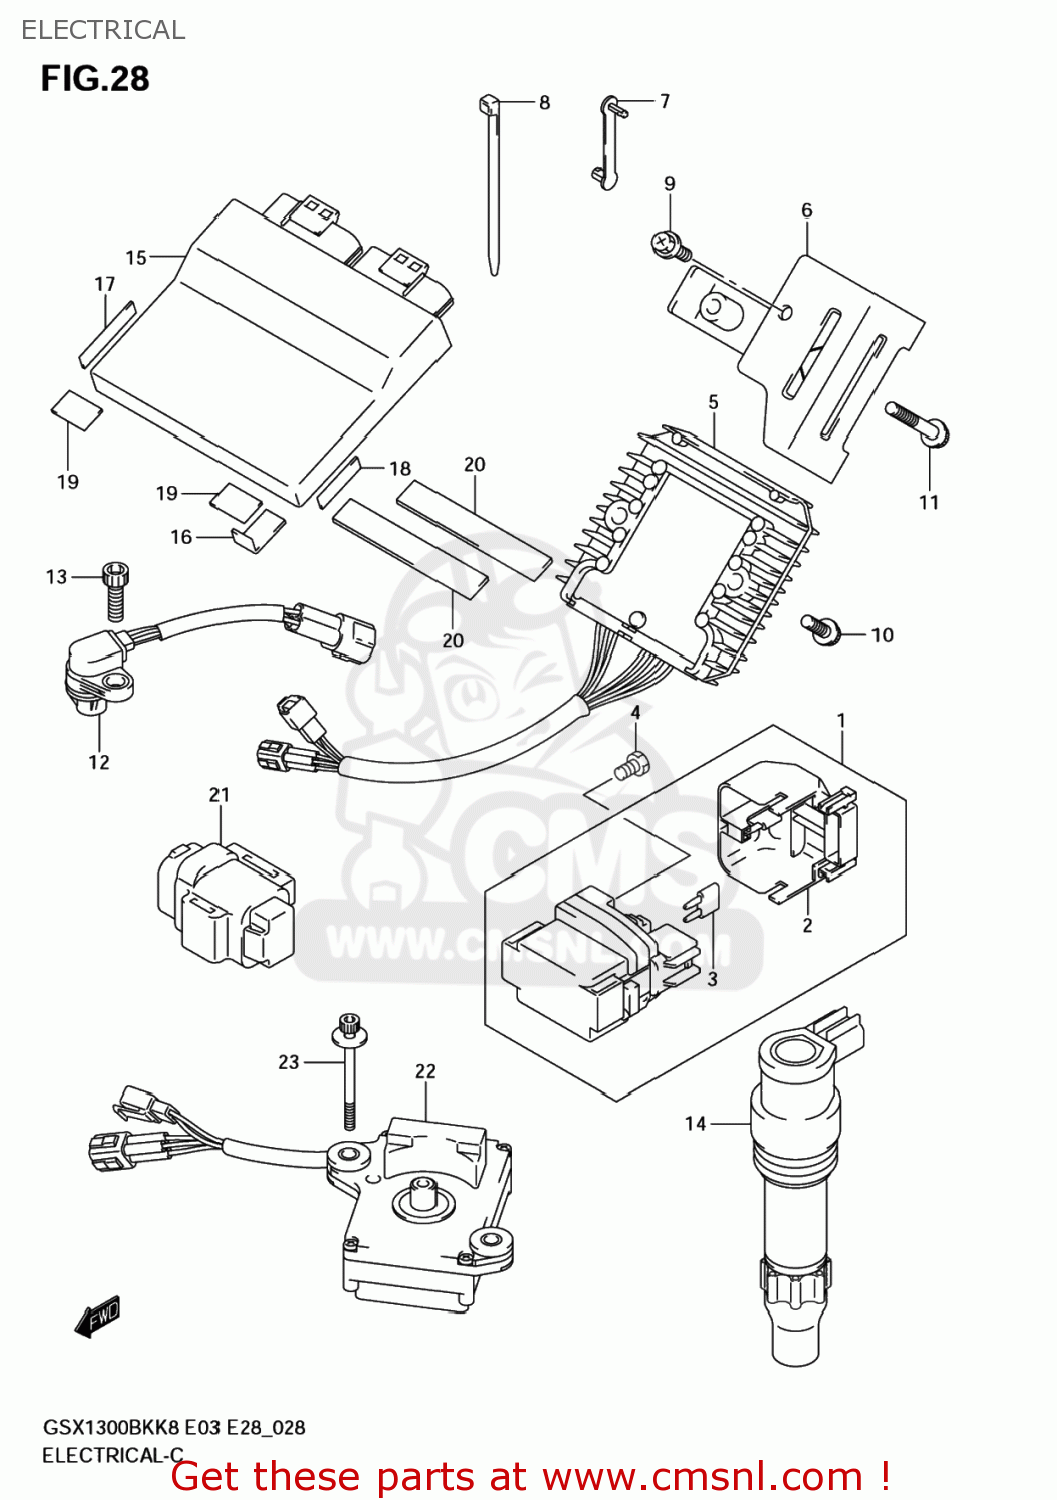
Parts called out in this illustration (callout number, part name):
1	RELAY ASSY,STARTING MOTOR
2	COVER
3	FUSE(30A)
4	SCREW(6X8)
5	RECTIFIER ASSY
6	COVER,RECTIFIER
7	CLAMP(L:63)
8	CLAMP(L:100)
9	SCREW
10	BOLT
11	BOLT
12	SENSOR ASSY,CAM POSITION
13	BOLT
14	COIL ASSY,IGNITION
15	CONTROL UNIT,FI
16	PROTECTOR(20X90)X2
17	PROTECTOR(20X90)X2
18	PROTECTOR(20X90)X2
19	PROTECTOR(170X95X3.0)
20	PROTECTOR(20X90)X2
21	SENSOR ASSY,FUEL CUT
22	ACTUATOR ASSY,EXHAUST CONTROL
23	BOLT(6X60)
